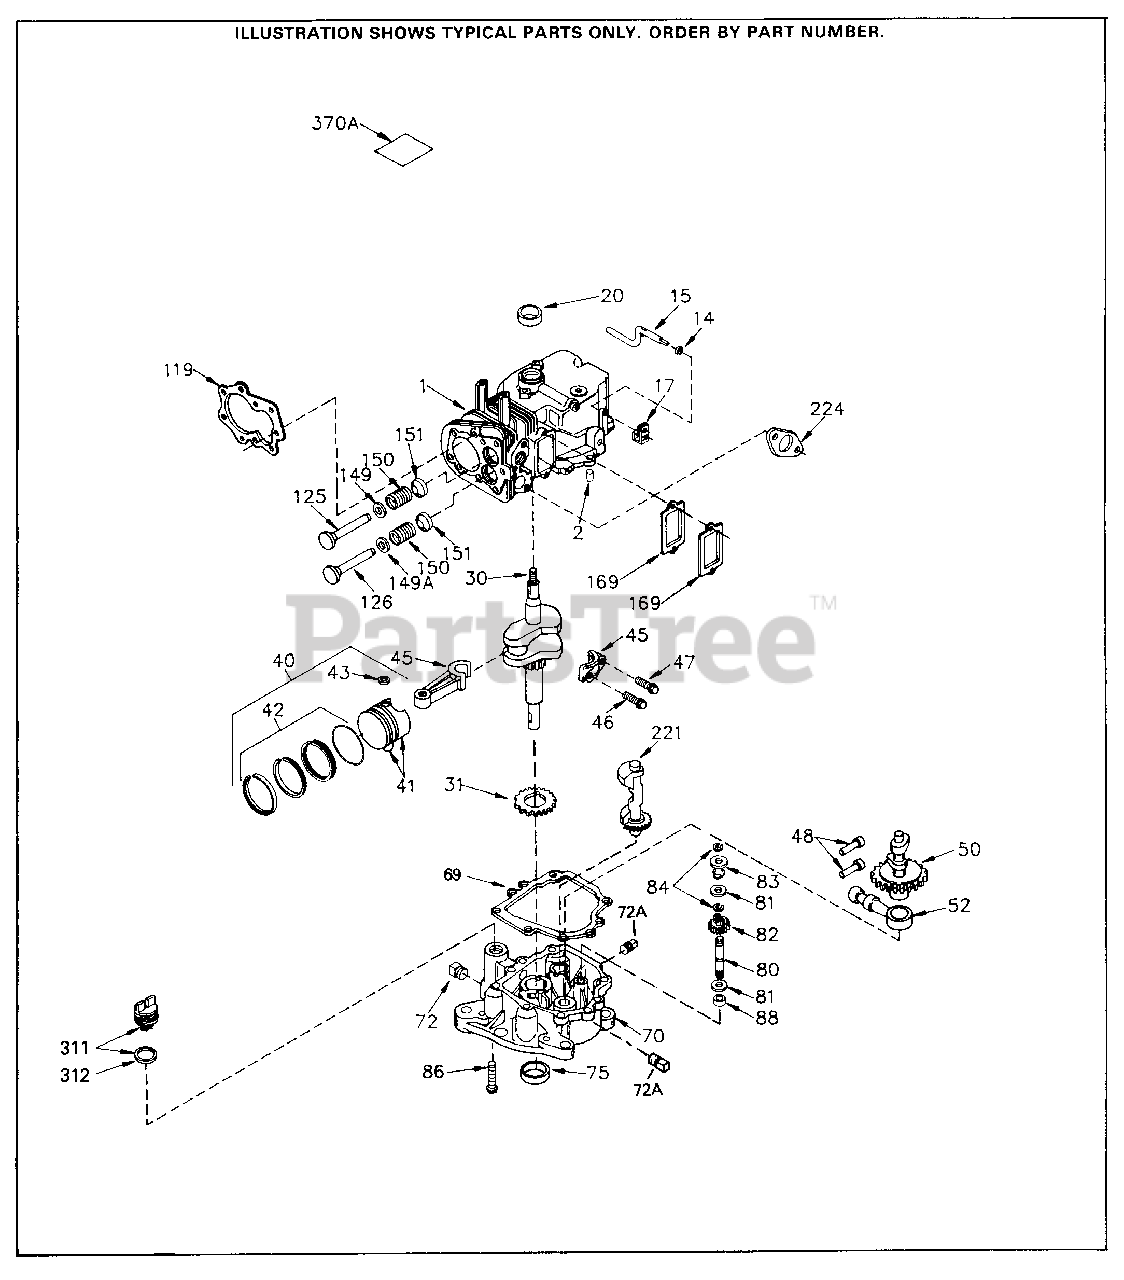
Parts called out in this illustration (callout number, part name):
1	"Cylinder (Incl. 2 & 20))
2	Dowel Pin
14	Flat Washer
15	Governor Rod
17	Governor Lever Clamp
20	Oil Seal
30	Crankshaft
31	Counterbalance Gear
40	Piston, Pin & Ring Set (.020" OS)
40	Piston, Pin & Ring Set (Std.)" Bore)
40	Piston, Pin & Ring Set (.010" OS)
41	Piston & Pin Ass'y. (Std.) (Incl. 43) -5/16")
41	Piston & Pin Ass'y. (.010" OS) Incl. 43
41	Piston & Pin Ass'y. (.020" OS) Incl. 43
42	Ring Set (Std.) (3-5/16")
42	Ring Set (.010" OS)
42	Ring Set (.020" OS)
43	Piston Pin Retaining Ring
45	Connecting Rod Ass'y. (Incl. 46 & 47)
46	Connecting Rod Bolt
47	Connecting Rod Bolt
48	Valve Lifter
50	Camshaft (MCR)
52	Oil Pump Assy.
69	Mounting Flange Gasket
70	Mounting Flange (Incl. 72, 72A, 75 & 80) 80)
72	Oil Drain Plug
72A	Oil Drain Plug (3/8-18)
75	Oil Seal
80	Governor Shaft
81	Flat Washer
82	Governor Gear Ass'y. (Incl. 81)
83	Governor Spool
84	Retaining Ring
86	Screw, 1/4-20 x 1-3/16"
88	Governor Gear Spacer
119	Cylinder Head Gasket
125	Exhaust Valve (Std.)(Incl. 151)
125	Exhaust Valve (1/32" OS) (Incl. 151)
126	Intake Valve (Std.) (Incl. 151)
126	Intake Valve (1/32" OS) (Incl. 151)
149	Valve Spring Cap
149A	Intake Valve Seal Assy.
150	Valve Spring
151	Valve Spring Cap
169	Valve Cover Gasket
221	Counterbalance Weight Assy.
224	Intake Pipe Gasket
311	Oil Fill Plug (Incl. 312) also availa ble in Packaged Part #740079
312	Oil Fill Plug Gasket
370A	Lubrication Decal
